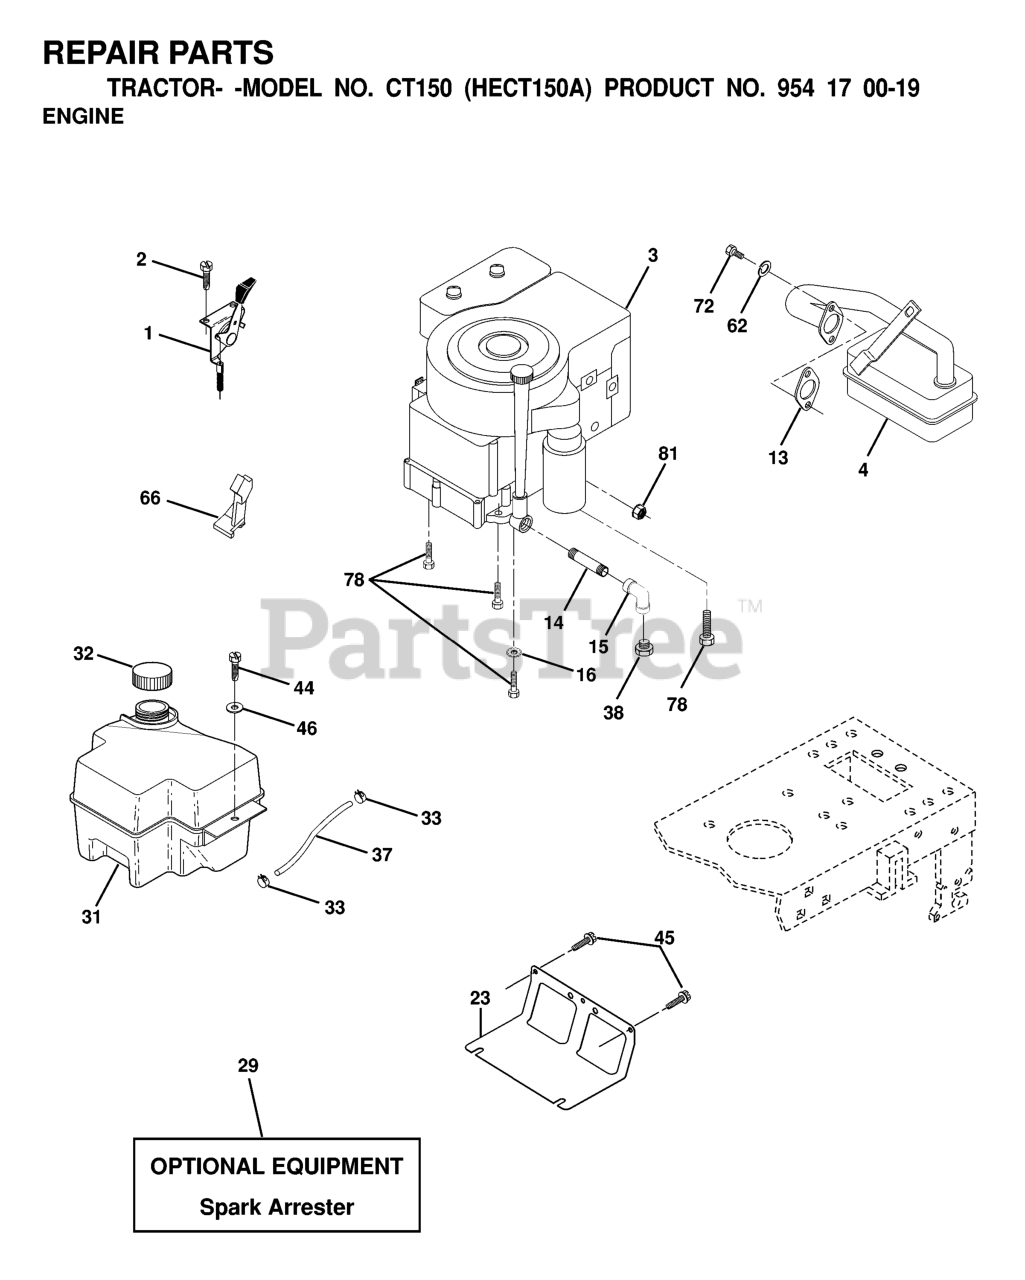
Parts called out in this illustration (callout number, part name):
1	CONTROL
2	SCREW LT
4	MUFFLER.LT.BRIGGS.14HP.IC/OHV
13	REPL BY 532 27 22-93
14	Nipple Pipe 3/8 Npt X 3-1/2
15	ELBOW
16	LOCKWASHER
23	SHIELD.BROWNING.DBR.GUARD
29	KIT.SPARK ARRESTOR 794945 B&S
31	FUEL TANK
32	FUEL CAP
33	HOSE CLAMP
37	LINE.FUEL.20
44	SCREW HEX CRT
45	SCREW 3/8-16X3/4
46	WASHER
62	WASHER.LOCK.HVY.HLCL.SPR.5/16
66	STOP THROTTLE
72	SCREW
78	SCREW.3/8-16
81	NUT FLANGE 1/4-20 STARTER NUT
